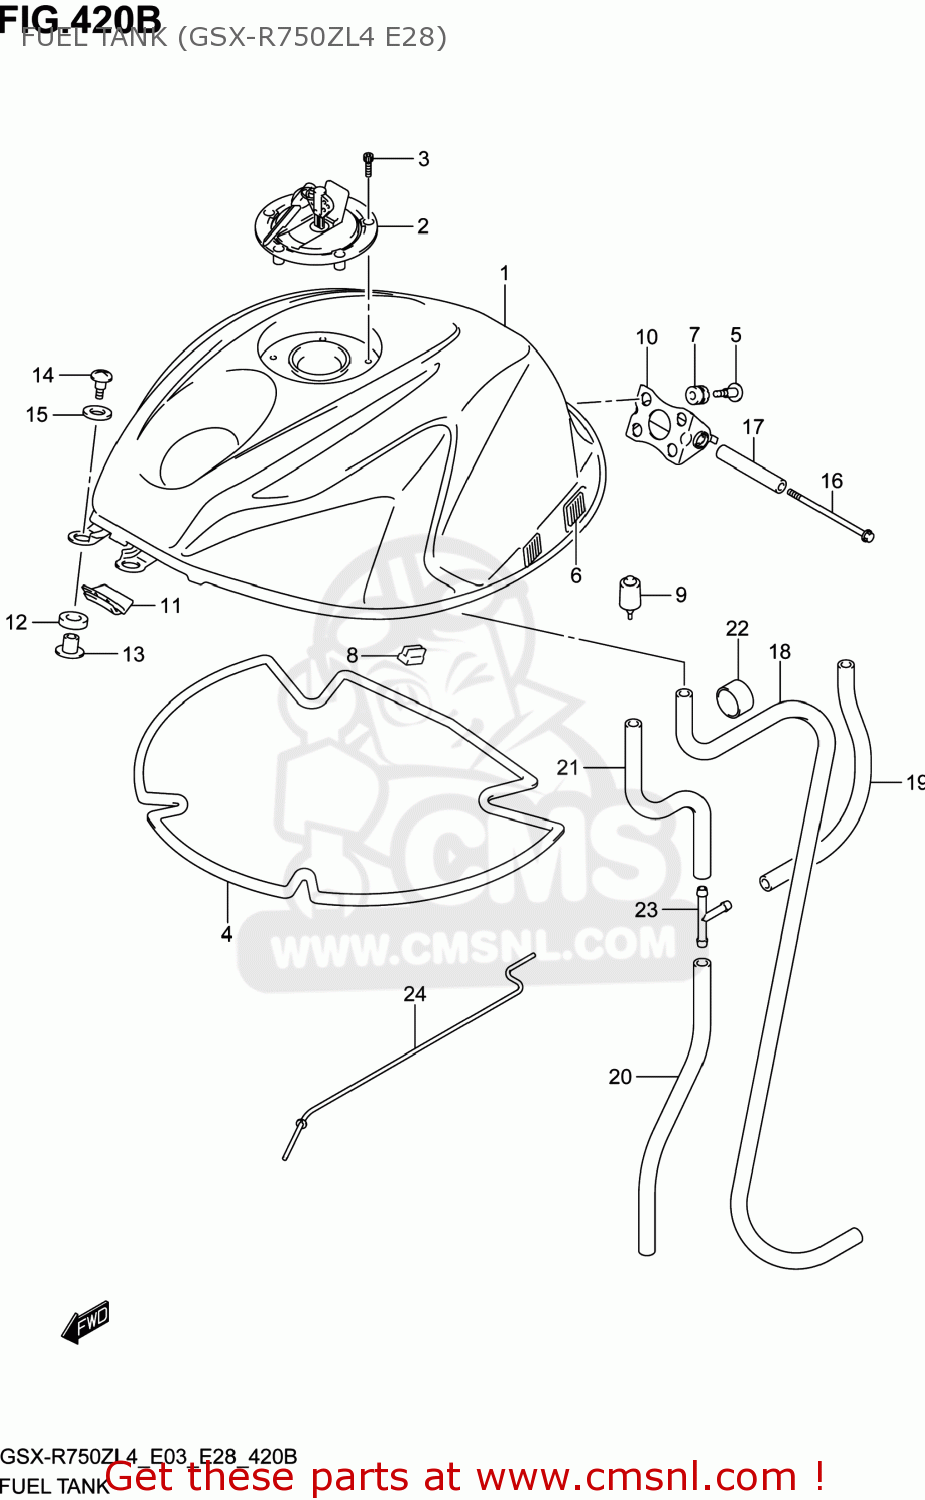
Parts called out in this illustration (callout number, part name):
1	TANK ASSY,FUEL(RED)
2	CAP SET,FUEL TANK
3	BOLT(5X20)
4	SHIELD,FUEL TANK HEAT
5	SCREW,FUEL TANK RR BRACKET
6	FASTENER
7	CUSHION
8	CUSHION,FUEL TANK COVER
9	CUSHION,FUEL TANK RR
10	BRACKET,FUEL TANK NO.1
11	RUBBER,FUEL TANK FR
12	CUSHION,FUEL TANK FR
13	SPACER,FUEL TANK FR
14	SCREW(6X25)
15	WASHER(6,5X22X1.6)
16	BOLT(6X110)
17	SPACER,FUEL TANK RR
18	HOSE,FUEL TANK WATER DRAIN
19	HOSE,FUEL TANK BREATHER NO.1
20	HOSE,FUEL TANK BREATHER NO.2
21	HOSE,VACUUM
22	HOSE(12X16X600)
23	3 WAY
24	STAY,FUEL TANK
